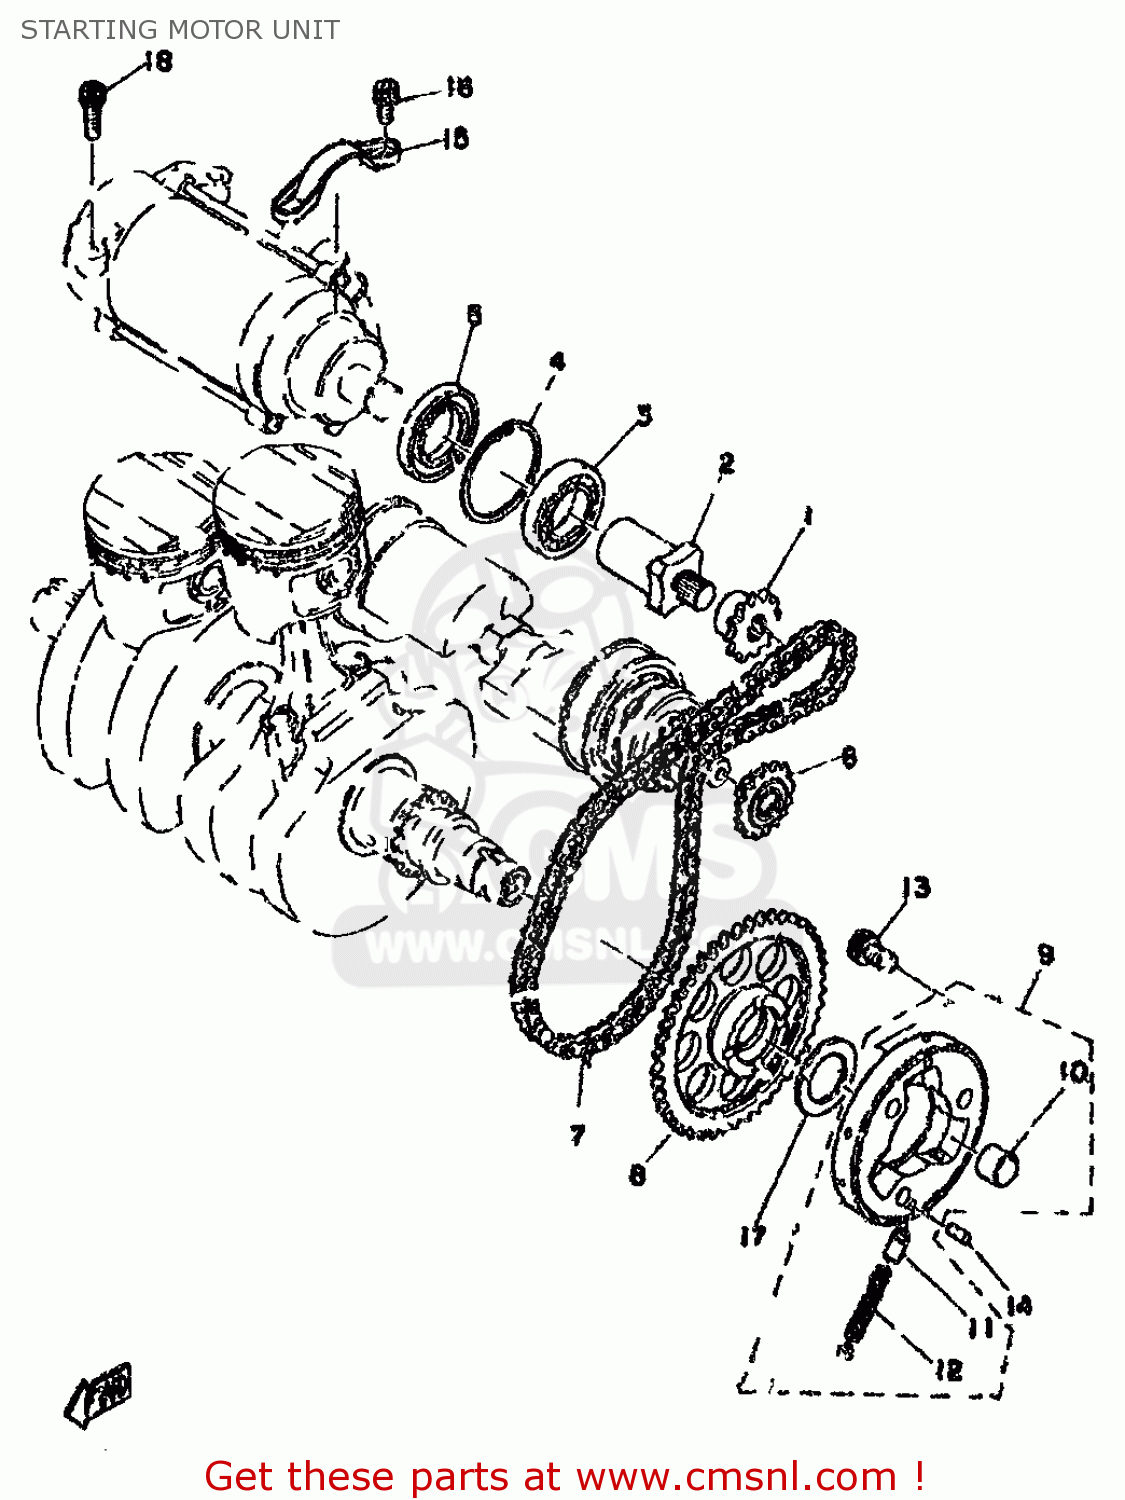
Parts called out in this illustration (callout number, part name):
1	SPROCKET, STARTER 1
2	SHAFT
3	BRG,R-B 6005 47MM 80G NT
4	CIRCLIP
5	OIL SEAL (25X45X7-371)
6	SPROCKET, STARTER IDLE
7	CHAIN,STARTER (371) 219HT-82LE
8	STARTER WHEEL ASSY
9	STARTER CLUTCH OUTER ASSEMBLY
10	PIN, DOWEL (371)
11	CAP, STARTER CLUTCH SPRING
12	SPRING COMPRESSION341155840300
13	BOLT
14	PIN, DOWEL (341)
15	HOLDER,STRTG MRTR
16	BOLT (341)
17	WASHER PLATE 131156530000
18	BOLT
